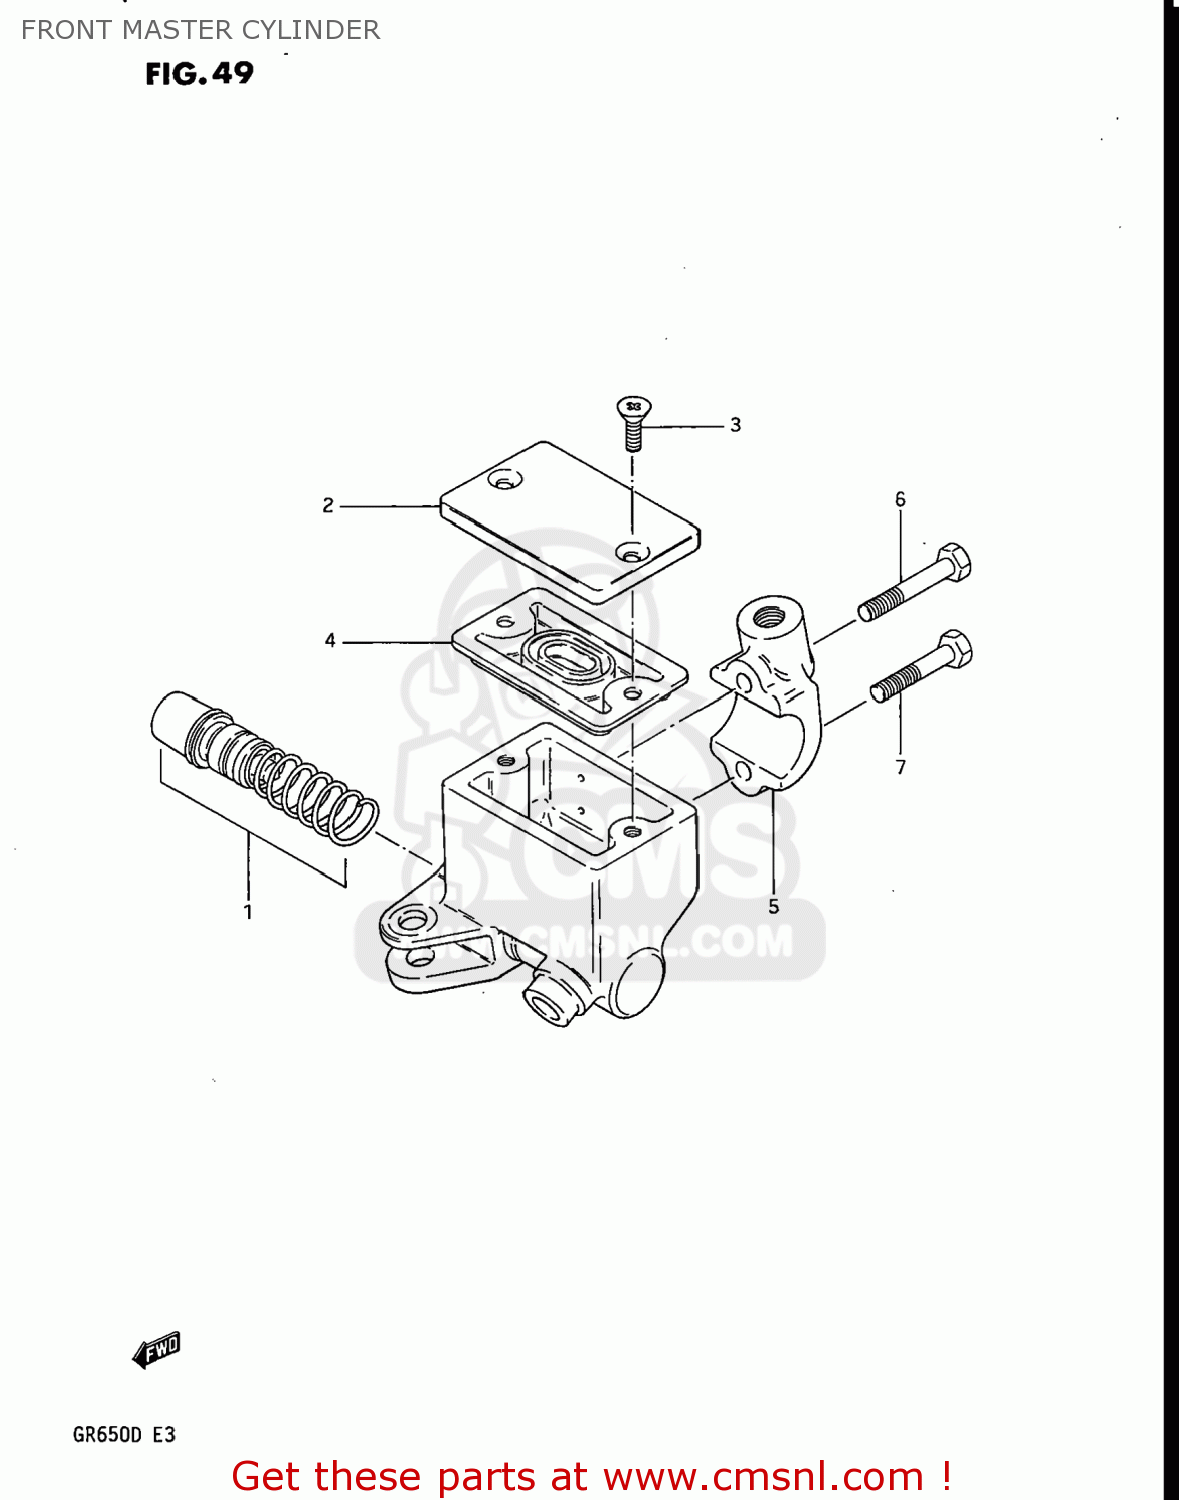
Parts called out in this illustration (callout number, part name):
1	PISTON & CUP SET
2	CAP,MASTER CYLINDER,REAR
3	SCREW,RESERVOIR CAP
4	DIAPHRAGM,MASTER CYLINDER
5	HOLDER
6	BOLT,MASTER CYLINDER H
7	BOLT,MASTER CYLINDER H
